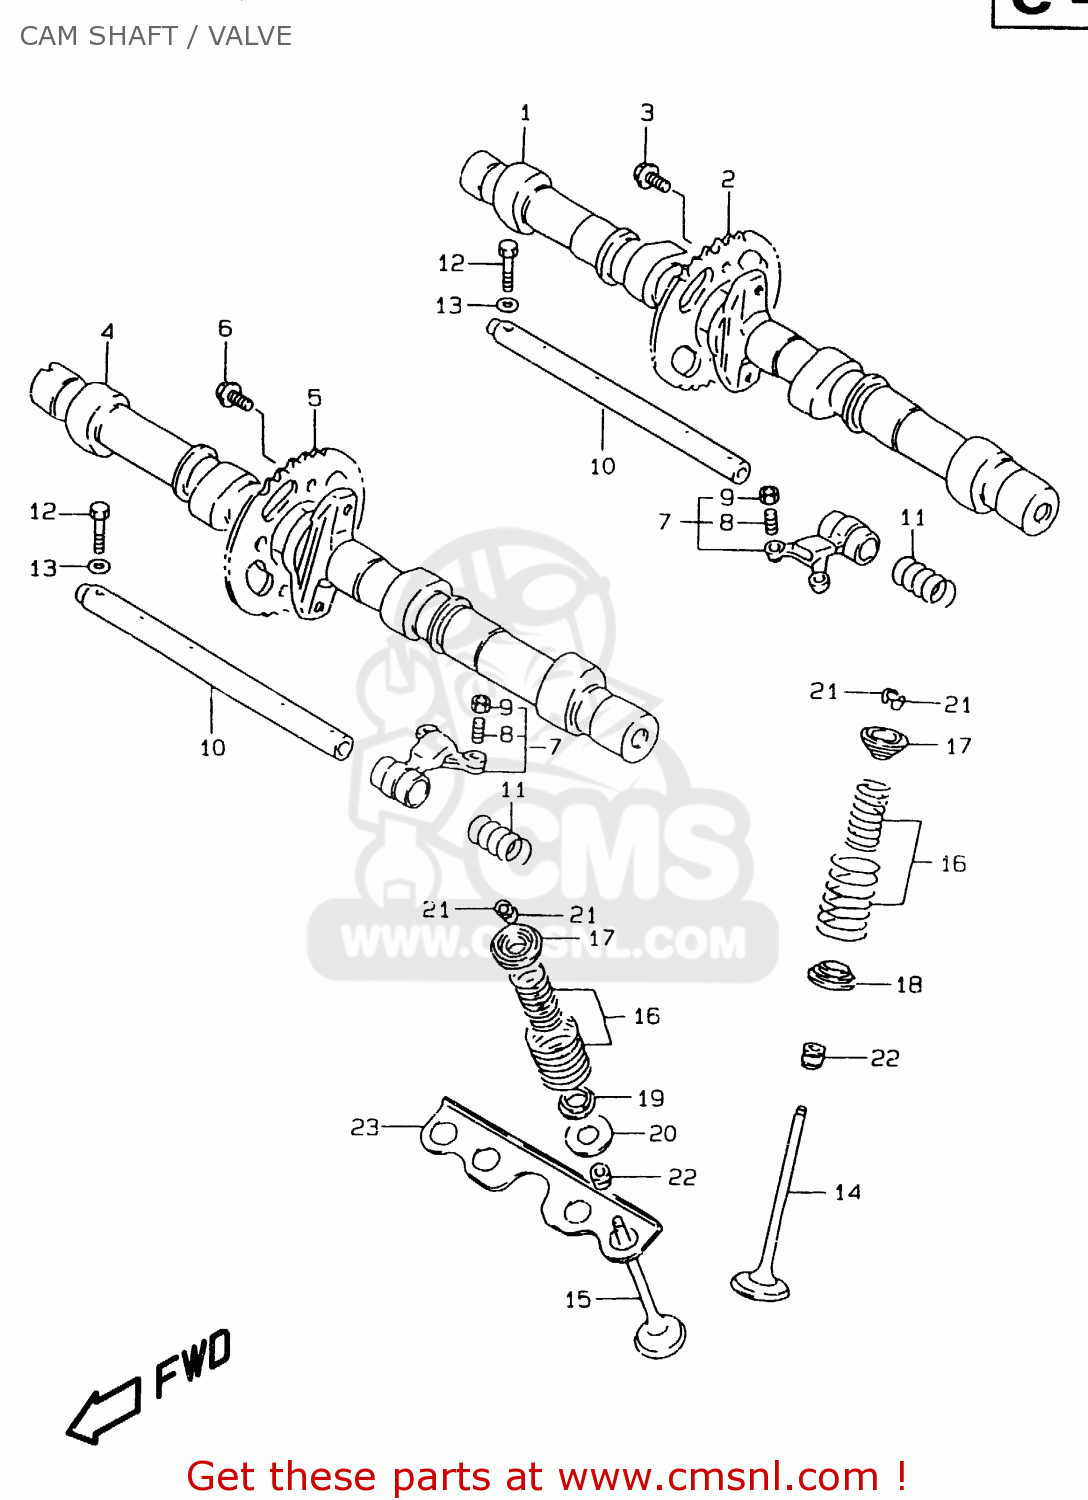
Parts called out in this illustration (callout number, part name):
1	CAMSHAFT,INTAKE
2	SPROCKET,CAMSHAFT
3	BOLT(7X11)
4	CAMSHAFT,EXHAUST
5	SPROCKET,CAMSHAFT
6	BOLT(7X11)
7	ARM,VALVE ROCKER
8	SCREW,TAPPET ADJUSTING
9	NUT,TAPPET ADJUSTING
10	SHAFT,VALVE ROCKER ARM
11	SPRING
12	BOLT
13	WASHER
14	VALVE,INTAKE
15	VALVE,EXHAUST
16	SPRING SET,VALVE
17	RETAINER,VALVE SPRING
18	SEAT,VALVE SPRING
19	SEAT,VALVE SPRING EXH INNER
20	SEAT,VALVE SPRING EXH OUTER
21	COTTER VALVE
22	SEAL,OIL(5X10X9.7)
23	PLATE,VALVE SEAT
